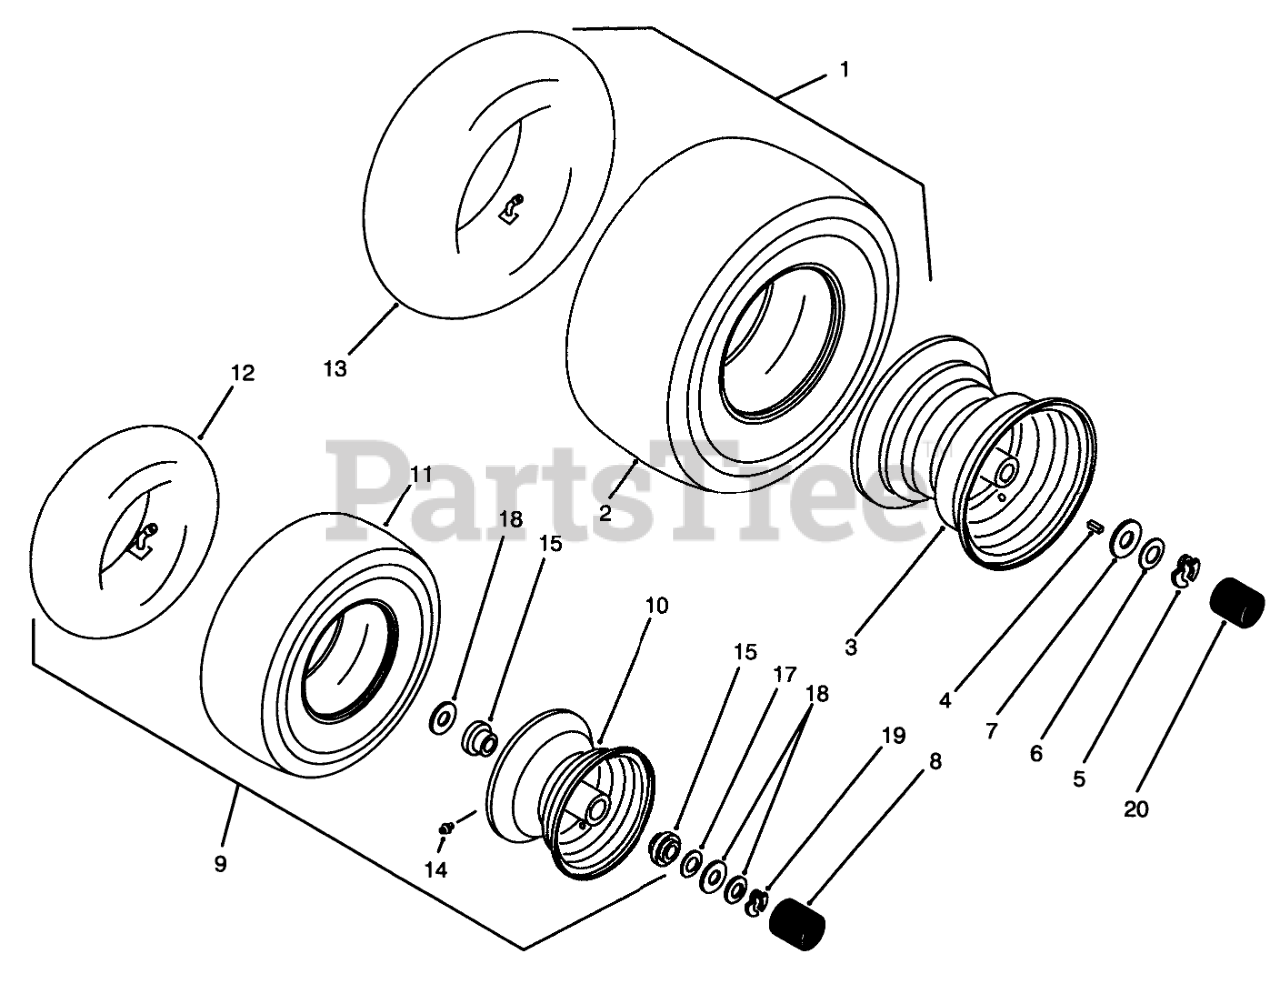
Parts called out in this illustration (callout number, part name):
1	Rear Wheel-Assembly 18 x 9.50 x 8 (Incl. Ref. #2, 3, & 13)
2	TIRE-18X9.50-8 TT RS
2	TIRE-KNOBBY
3	WHEEL ASS'Y 8"X7
4	KEY-SQUARE
5	RING-RETAINING
6	Washer
8	HUB CAP-FLAT BLACK
9	Front Wheel Assembly 11 x 4.00-5 (Incl. Ref. #10-12, 14 & 15)
10	Front Wheel Assembly (Incl. Ref. #14 & 15)
11	TIRE 11 X 400-5 RIB
12	TUBE-TIRE 11X4.00-5
13	TUBE-TIRE
14	ZERK-GREASE
15	BEARING-WHEEL
17	WASHER-SHIM
18	WASHER-WHEEL
19	KLIP-RING .75"
20	HUBCAP
